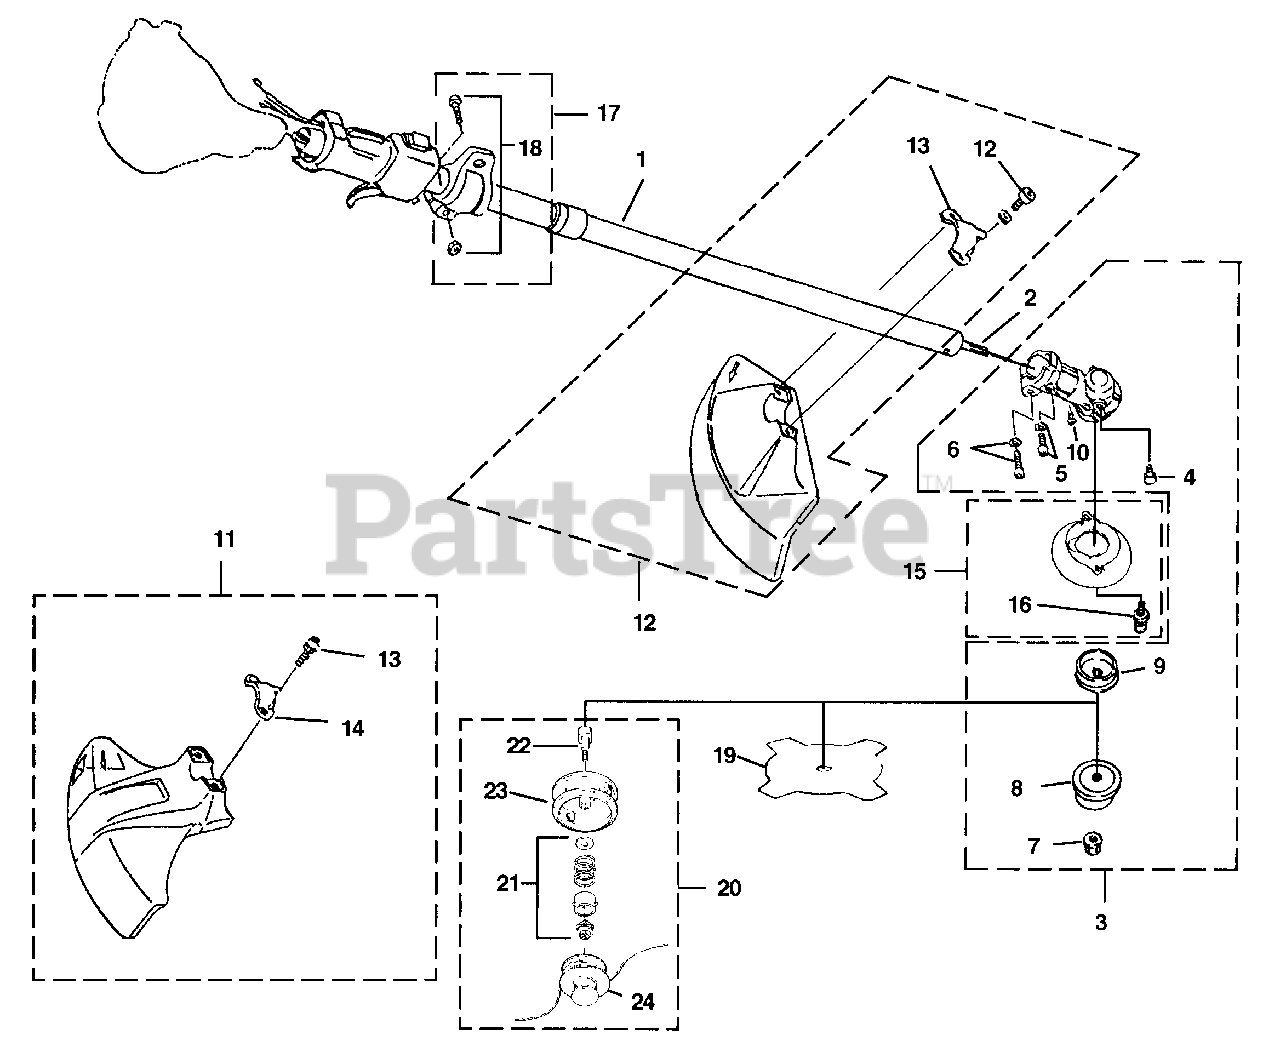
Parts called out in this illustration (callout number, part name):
1	DRIVESHAFT HOUSING
2	DRIVESHAFT
3	GEAR HEAD
4	BOLT - Grease (M8)
5	BOLT ASSEMBLY (M5 X 12 SW)
6	BOLT ASSEMBLY (M5 X 25 SW)
7	NUT (M8)
8	WASHER - Cupped
9	WASHER - Flange
10	SCREW (M5 x 6)
11	DEFLECTOR ASSEMBLY (Grass)
12	DEFLECTOR ASSEMBLY (Blade)
13	BOLT (M6 x 30)
15	GRASS GUARD
16	SCREW - Socket Hd (M5 x 12 W SW)
17	HANGER ASSEMBLY
18	SCREW ASSEMBLY (M5 x 20)
19	QUAD BLADE (GT25)
20	STRINGHEAD ASSEMBLY (.095)
21	REPAIR KIT
22	BOLT, Shaft
23	HOUSING W/Eyelets
24	SPOOL & STRING (.095)
